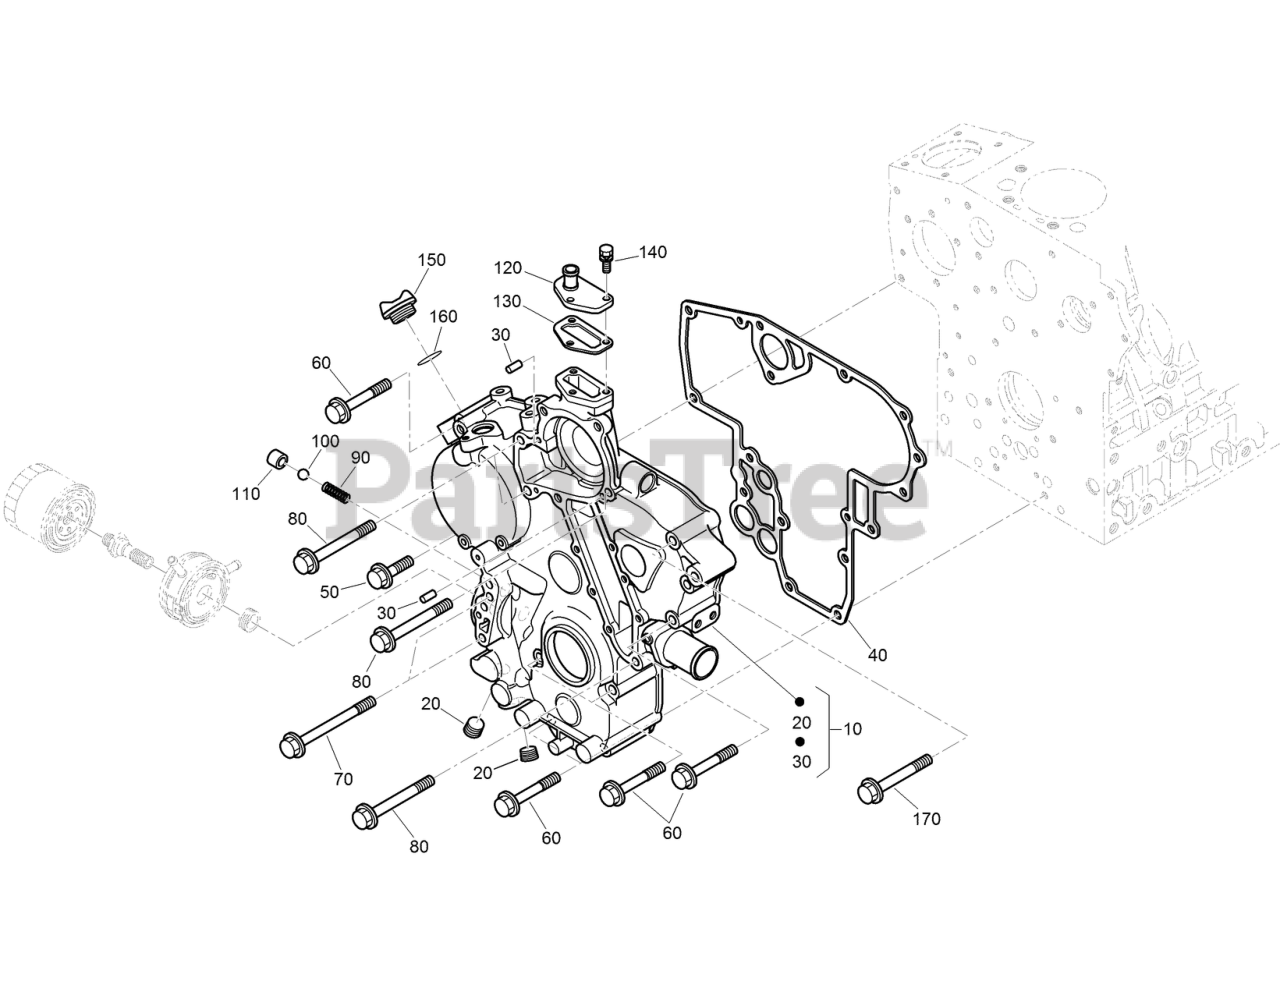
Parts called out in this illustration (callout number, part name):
10	CASE-GEAR
30	PIN-STRAIGHT
40	GASKET-CASE, GEAR
50	BOLT-FLANGE
60	BOLT-SEMS
70	BOLT-SEMS
80	BOLT-FLANGE
90	SPRING
100	SEAT-VALVE
120	FLANGE-RETURN, WATER
130	GASKET-FLANGE, RETURN
160	O-RING
170	BOLT-HEX
